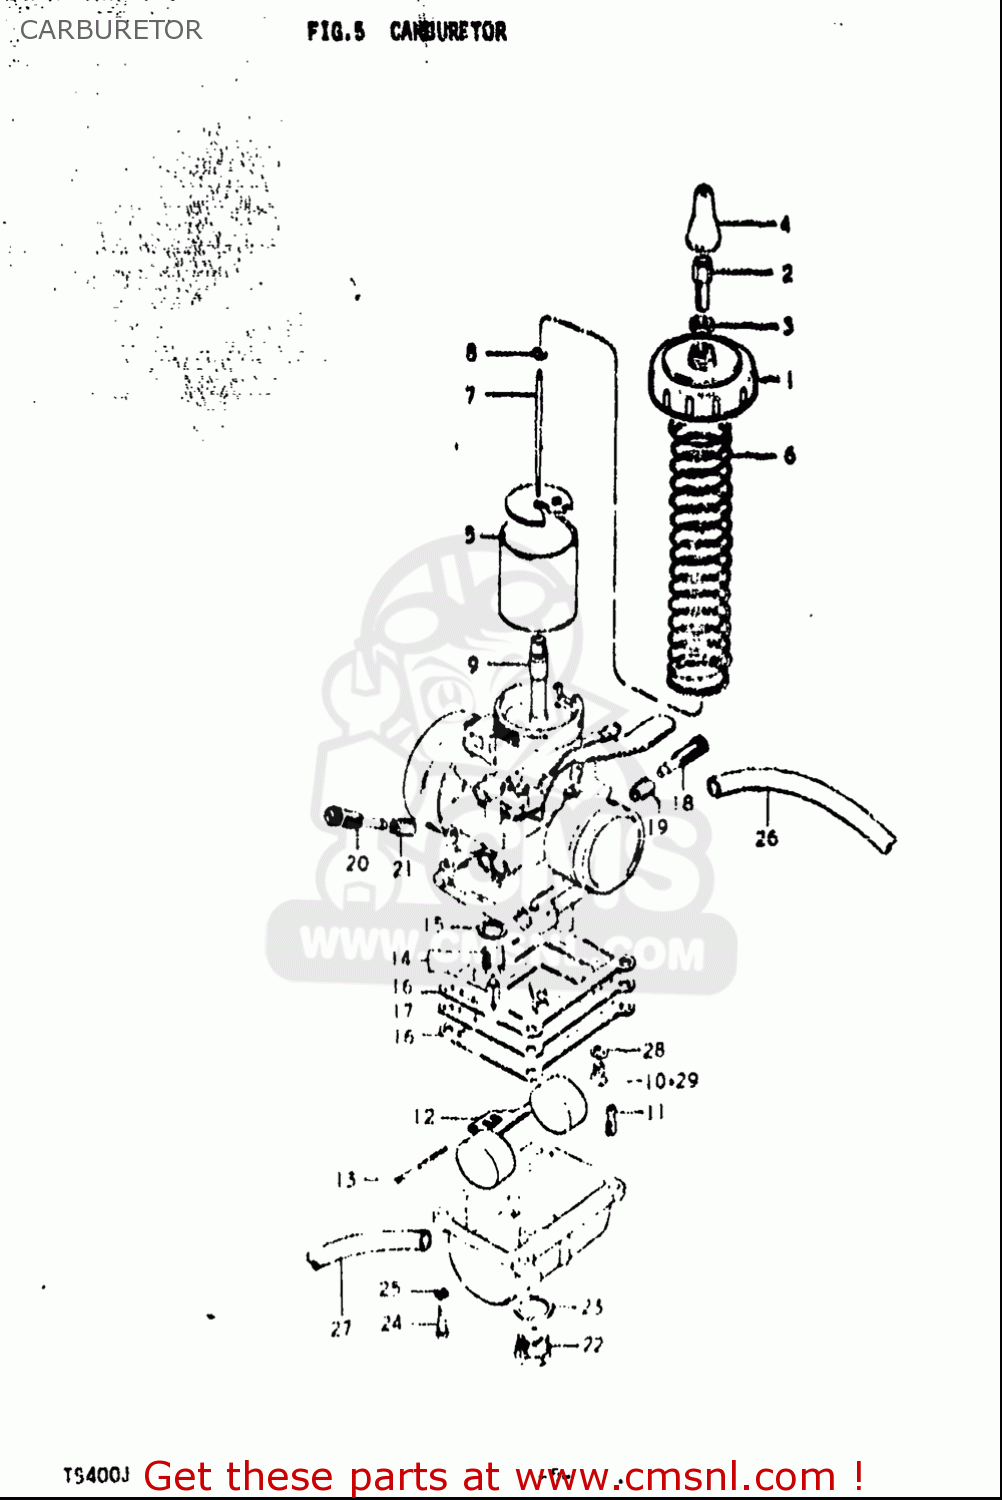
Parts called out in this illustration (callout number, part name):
2	ADJUSTER,CABLE
3	NUT
4	CAP,RUBBER
8	CLIP
10	JET,MAIN(210)
11	JET,PILOT(40)
12	FLOAT
14	VALVE ASSY,NEEDLE
15	GASKET,MAIN JET HOLDER (NAS)
19	SPRING,THROTTLE SCREW
20	SCREW,PILOT AIR
21	SPRING
23	GASKET,DRAIN PLUG
25	WASHER,LOCK
26	HOSE(3.5X6.5X600)
27	HOSE(3.5X6.5X600)
28	WASHER
29	JET,MAIN(180)
